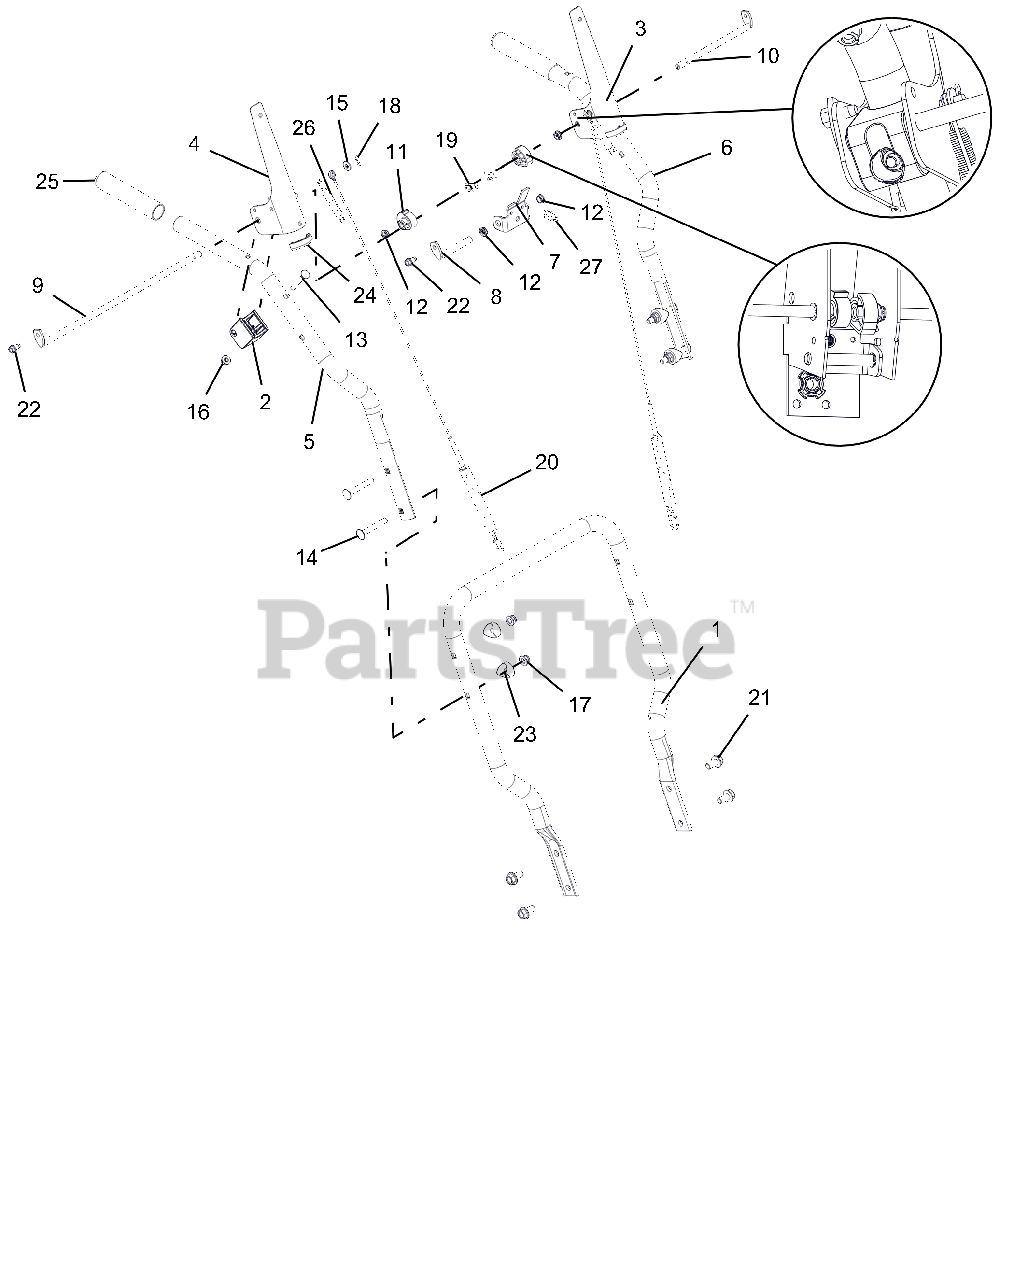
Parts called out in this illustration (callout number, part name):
1	HANDLEBAR, LOWER (COMPACT)
2	BLOCK, CLUTCH PADDLE
3	LEVER, CLUTCH-LH
4	LEVER, CLUTCH-RH
5	HANDLEBAR, UPPER - RH
6	HANDLEBAR, UPPER - LH
7	BRACKET, INTERLOCK ARM
8	ROD, PIVOT - INTERLOCK
9	ROD, PADDLE MOUNT - LONG
10	ROD, PADDLE MOUNT - SHORT
11	CAM, INTERLOCK
12	BUSHING, POLYLINER-.38 SNAPIN
13	BLT-RDHDXLSQNK .25-20X2.0 G5YZ
14	@BLT-RDHDSQNK .31-18X2.25 G5YZ
15	@WSHR-FL-STL.281X.62X.065 YWZC
16	@NUT-LK-TOP-FLG .25-20 YWZC
17	@NUT-LK-NYL-FLG .31-18 YWZC
18	PIN-HAIR INT .06X.18X.77
19	PIN, SPRING CLIP
20	CABLE, AUGER & UPPER TRACTION
21	BLT-SERHFWH .38-16X.75 YWZC
22	SCR-TAP .25-20X.50 HWH TR YWZ
23	SPACER, HANDLEBAR
24	EDGING, CLUTCH PADDLE - 2.00"
25	HANDLE GRIP
26	SPRING, EXTENSION
27	SPRING-EXT .047X.438X1.45
